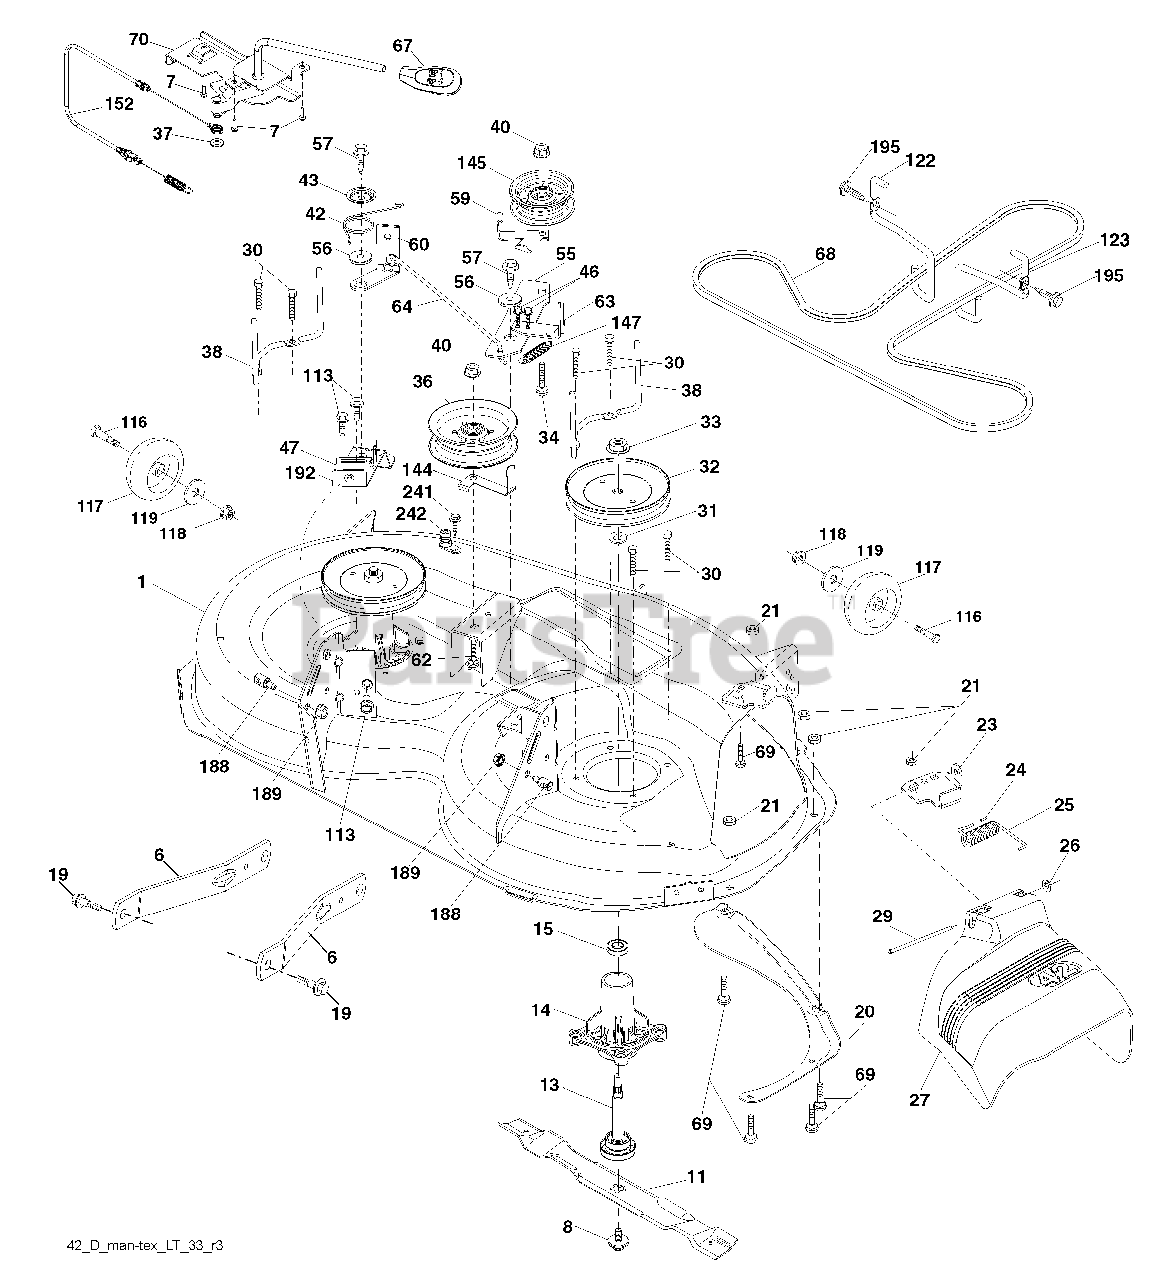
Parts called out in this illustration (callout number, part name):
1	Mower Housing
6	Arm Suspension
7	Screw #10 X .750 Bos Thread
8	Bolt/Washer Asm 7/16-20 Unf
11	Blade, 42" Hi-Lift (For Bagging Or Discharge)
13	Housing, Mandrel
14	Bearing, Ball, Mandrel
15	Bolt, Shoulder
19	Baffle, Vortex
20	Nut, Crownlock 5/16-18 Unc
21	Bracket, Deflector
23	Cap, Sleeve
24	Spring, Torsion, Deflector
26	Shield, Deflector
27	Rod, Hinge
29	Screw Thdrol Rolling Wsh Hd
30	Washer, Spacer
31	Pulley, Mandrel
32	Nut, Toplock, Flanged
33	Bolt Carr Sh. 3/8-16 X 1-1/2 Gr. 5
34	Pulley, Idler, Flat
36	Washer
37	Keeper Belt Mandrel
38	Nut, Lock Flg. 3/8-16 Unc
40	Spring Torsion Brake
42	Spring Torsion Retainer
43	Screw Thd Roll 1/4-20 X 5/8
46	Bracket Clutch Cable
47	Arm, Idler
55	Spacer, Retainer
56	Screw 3/8-16 X 1
57	Guard, Tuv Idler
59	Arm Brake Mower
60	Bolt Rd Hd Sq Nk 3/8-16 Unc X 2
62	Arm Brake Mower
63	Link Brake
64	Handle Clutch Cable
67	V-Belt
68	Bolt
69	Clutch Asm Manual
70	Screw 5/16-18
113	Bolt, Shoulder
116	Wheel, Gauge
117	Nut, Crownlock 3/8-1
118	Washer 13/32 X 7/8 X 14 Ga.
119	Keeper Belt Engine Lh
122	Keeper Belt Engine Rh
123	Keeper Belt
144	Pulley Idler
145	Spring Return
147	Manual Clutch Cable
152	Stud Fastener
188	Nut Lock Hex Flange
189	Bracket Brake Stand Lh
192	Screw 3/8-16 X 3/4
195	Screw Tt #10-32 5 3/8 Flange
241	Port Washout
242	Coupling Quick Connect
